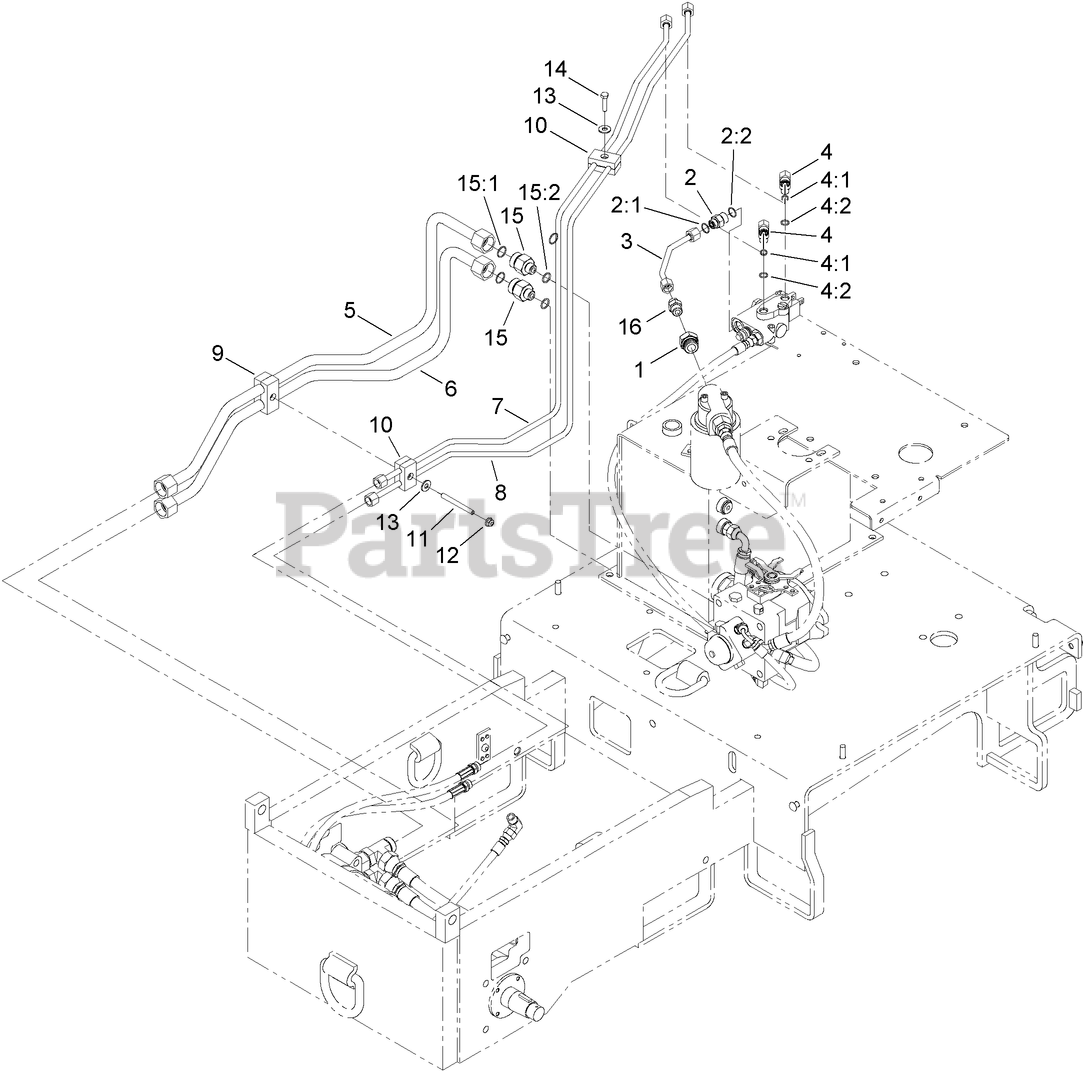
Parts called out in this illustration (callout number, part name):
1	FITTING-HYD
2	FITTING-STRAIGHT
2:1	O-RING
2:2	O-RING
3	HYD TUBE ASM
4	FITTING-ELBOW, 90 DEG
4:1	O-RING
4:2	O-RING
5	HYD TUBE ASM
6	HYD TUBE ASM
7	HYD TUBE ASM
8	HYD TUBE ASM
9	CLAMP-TWIN
10	CLAMP-TWIN
11	ROD-CLAMP, HOSE
12	NUT-HF, NI
13	WASHER-FLAT
14	SCREW-HH
15	FITTING-STR
15:1	O-RING
15:2	O-RING
16	FITTING-HYD
